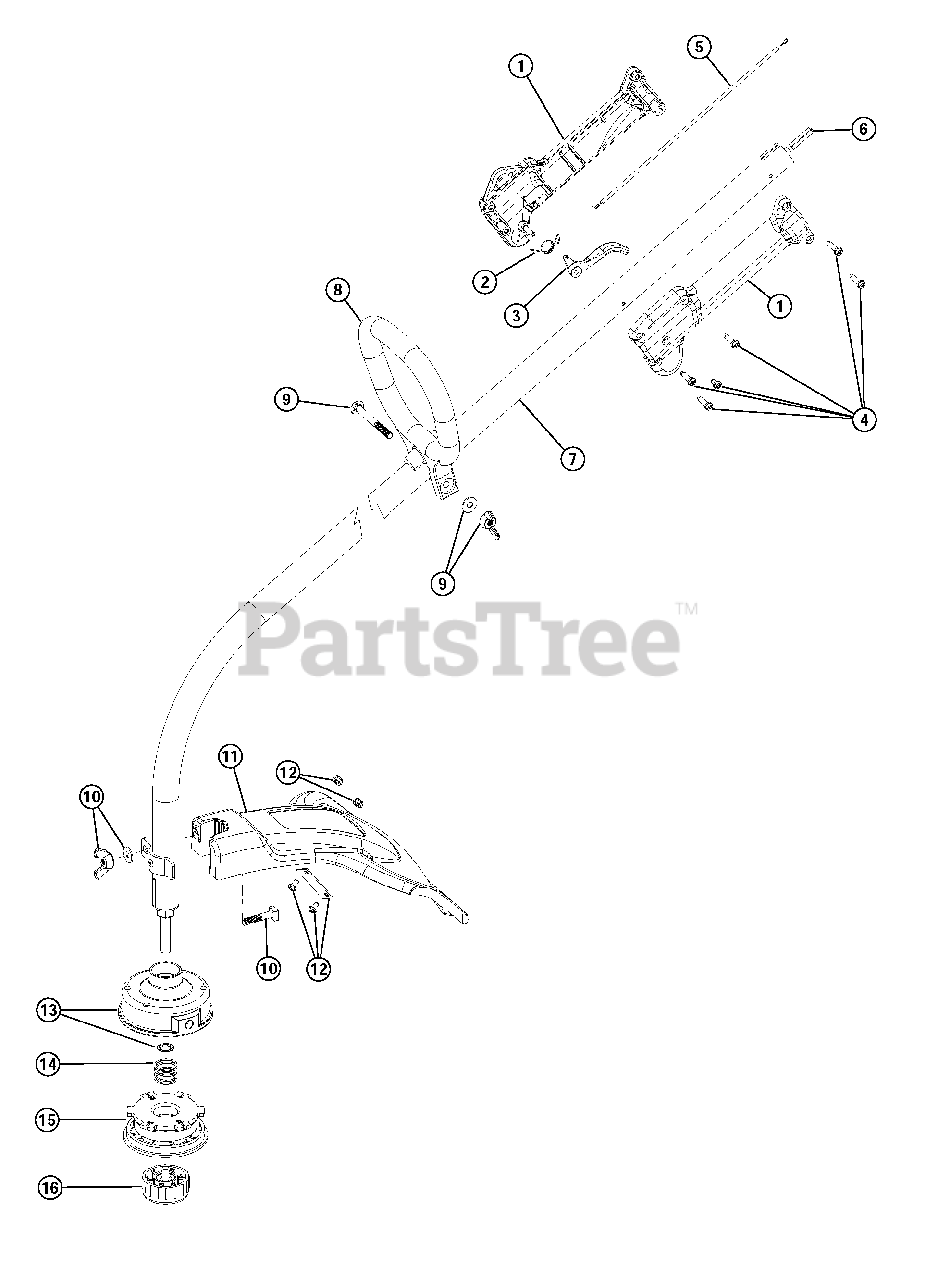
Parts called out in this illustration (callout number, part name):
1	Throttle Housing and Trigger Assembly
2	Throttle Trigger Spring
3	Throttle Trigger
4	Throttle Housing Screws
5	Throttle Cable
6	Flexible Drive Shaft
7	Drive Shaft Housing Assembly
8	D-Handle Assembly
9	D-Handle Hardware
10	Guard Mounting Hardware
12	Blade Assembly
13	Outer Reel w/Retainer
14	Spring
15	Inner Reel
16	Bump Knob
